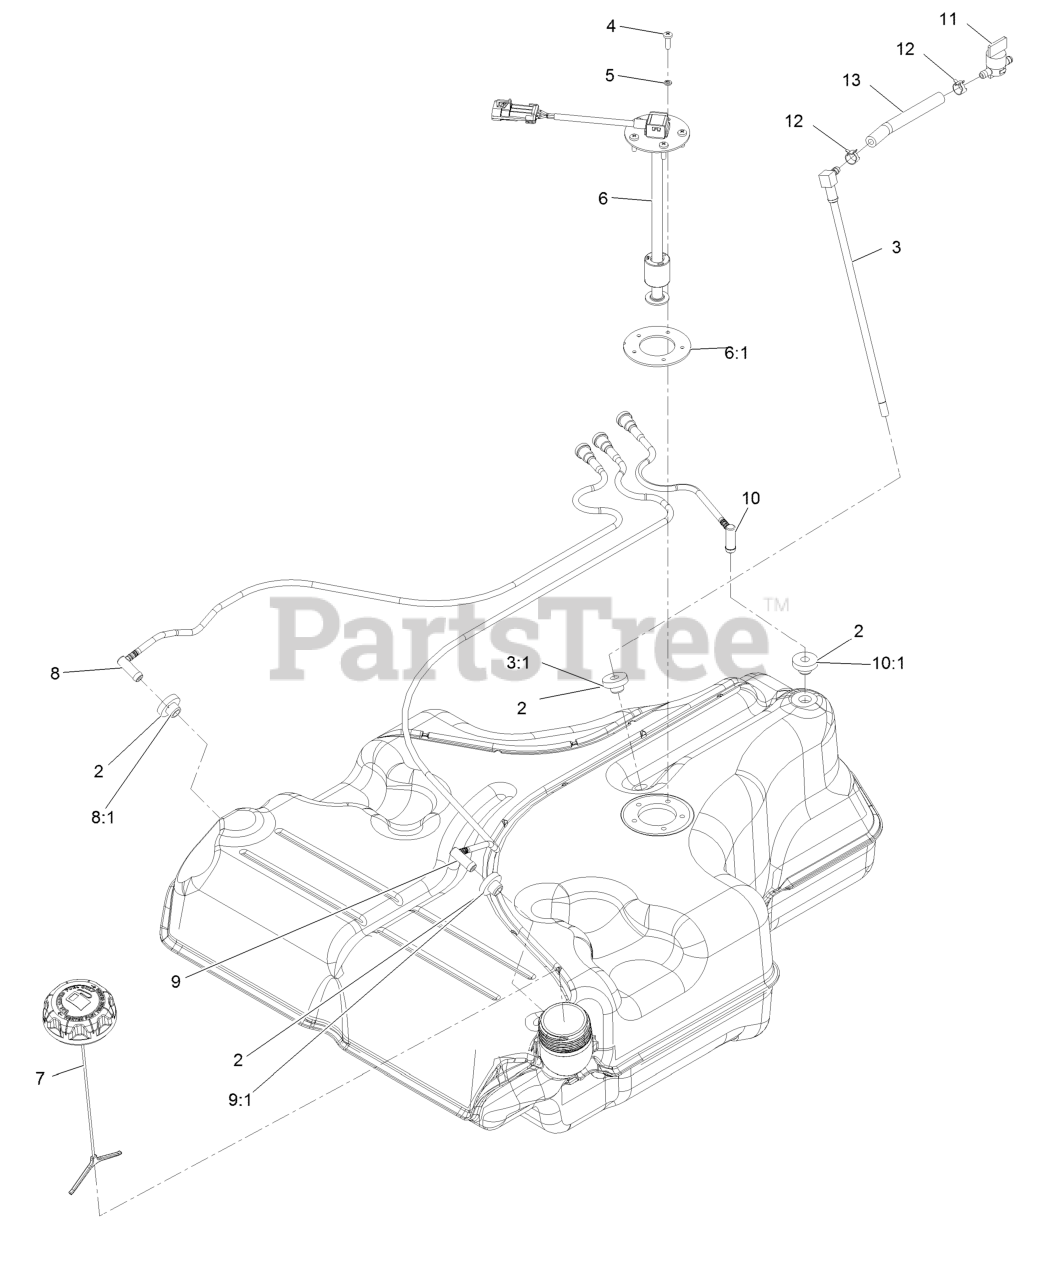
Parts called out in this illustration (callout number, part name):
2	Bushing
3	Fuel Line Kit (With Grommet)
3:1	Bushing
4	Screw-PPH
5	Washer-Lock
6	Float-Sender, Fuel
6:1	Gasket-Sender
7	Cap-Fuel, Ratcheting
8	RH Vent Line Kit (With Grommet)
8:1	Bushing
9	LH Vent Line Kit (With Grommet)
9:1	Bushing
10	Rear Vent Line Kit (With Grommet)
10:1	Bushing
11	Valve-Fuel
12	Clamp-Hose
13	Hose-Fuel
